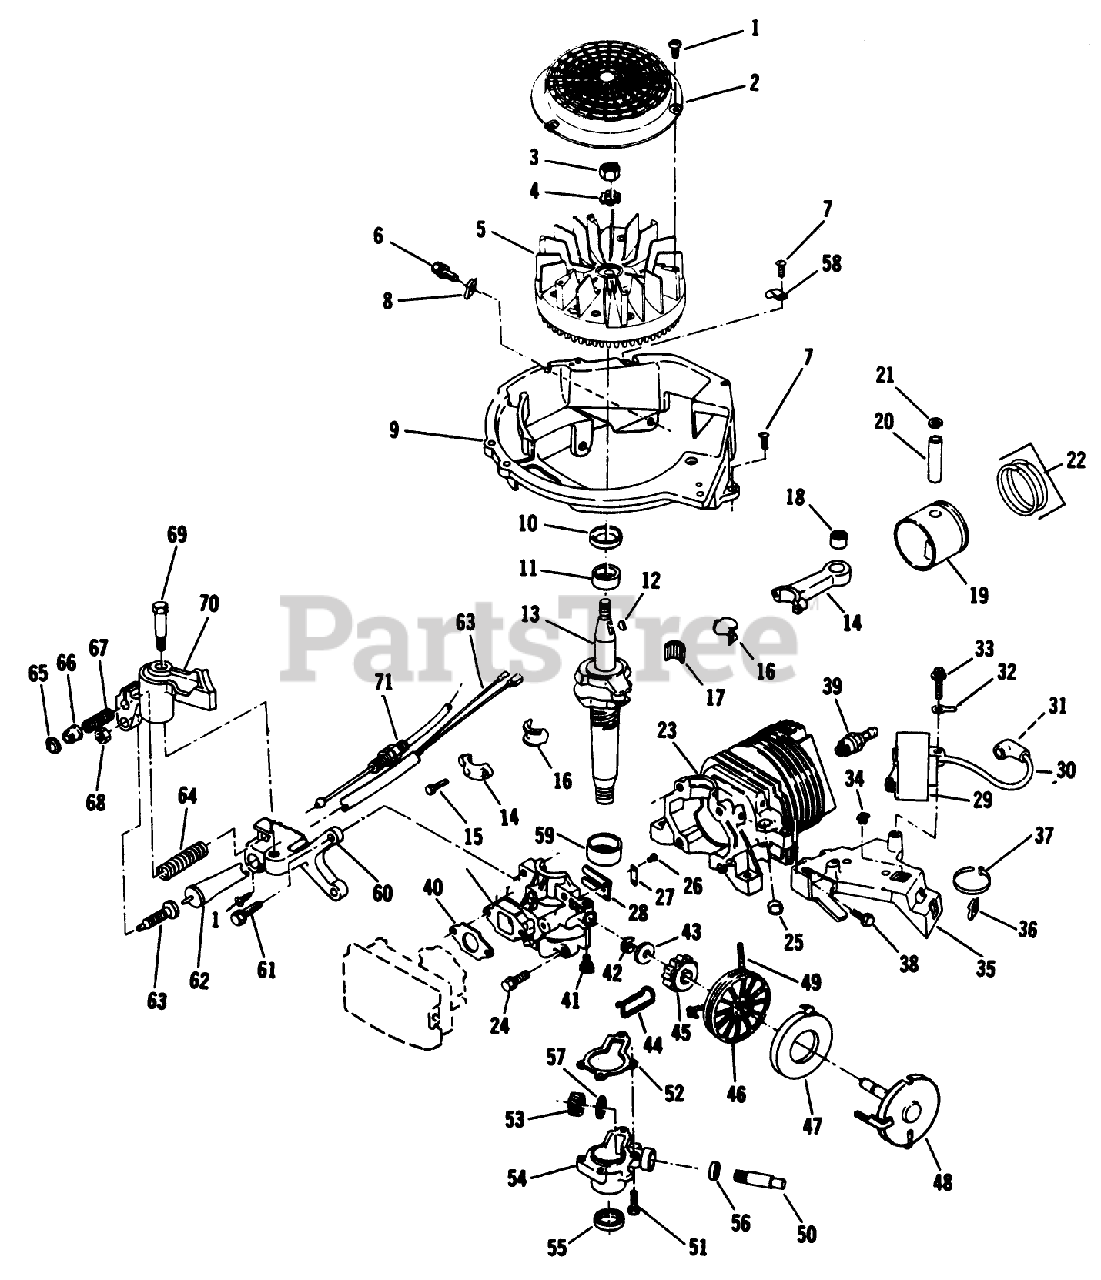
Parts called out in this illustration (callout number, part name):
1	SCREW F
2	SCREEN F'WHEEL S
3	NUT
6	SCREW-SEMS
7	SCREW F
11	BEARING V
12	KEY
15	SCREW-HSH
16	LINER ASM
18	BEARING AY F
22	RING-RETAINING
24	SCREW S
25	PLUG-CORE VF
27	PLATE-BACKUP, REED
30	HT LEAD&COVER XEV
32	TERMINAL S
34	NUT-CLIP
36	NUT - SPEED S
40	GASKET CARB S
43	WASHER S
46	PULLEY STARTER S
47	SPRING&RET.AY S
48	SPRING CUP&PIN S
49	ROPE-STARTER
52	GASKET S
53	GEAR, DR SHAFT S
55	SEAL-OIL
56	SEAL S
57	THRUST WASHER
59	BEARING S
60	BRACKET-BRAKE F
63	PLUNGER S
64	SPRING-BRAKE
65	RETAINER S
66	ACTUATOR-LEVER, BRAKE
67	SPRING
71	CONTROL CABLE
